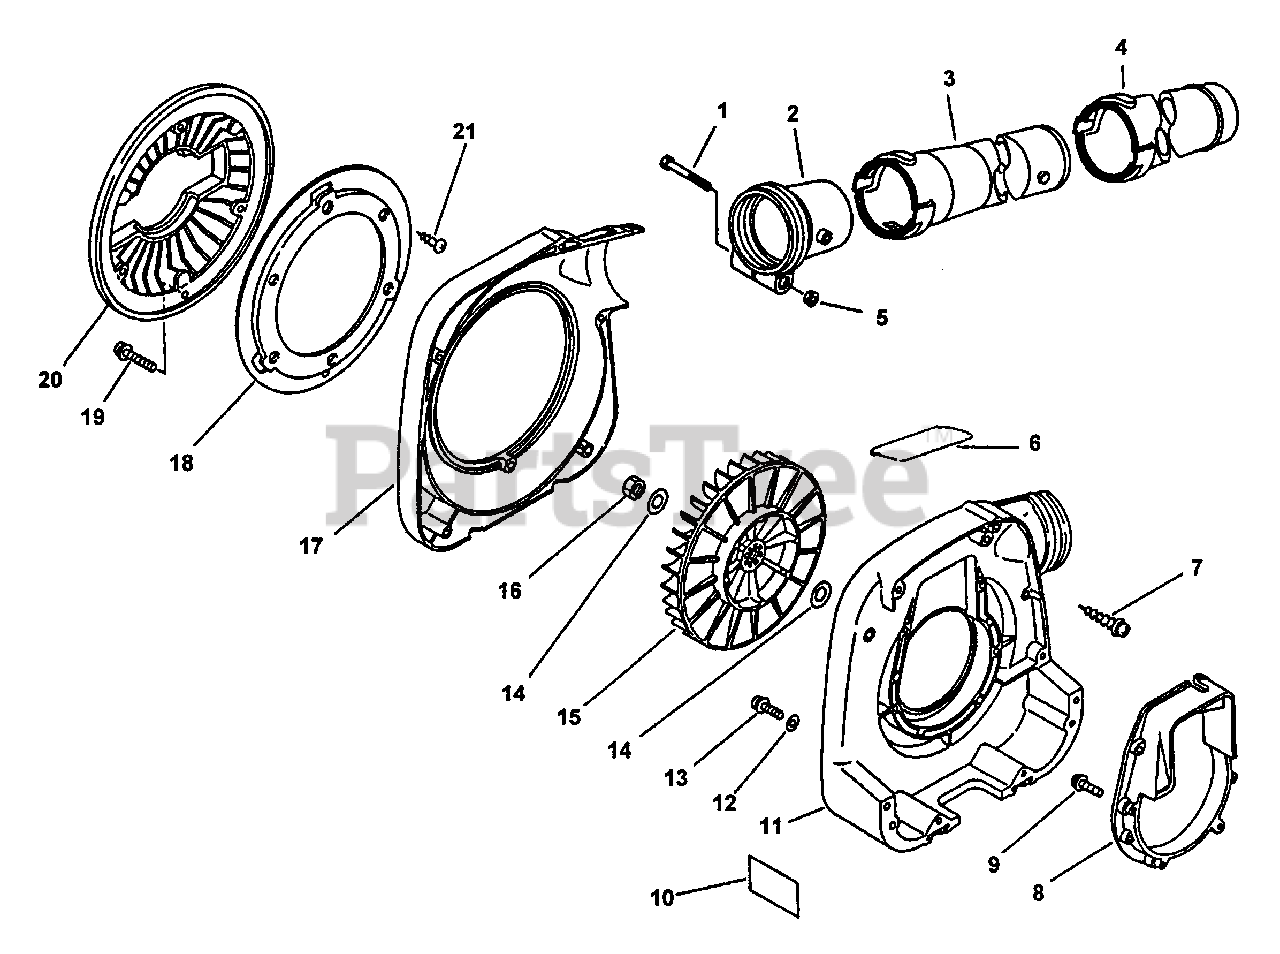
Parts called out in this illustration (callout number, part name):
1	SCREW - 5×60
2	ADAPTER, TUBE
3	TUBE, BLOWER - STRAIGHT
4	TUBE, BLOWER - NOZZLE
5	NUT, FLANGE M5
6	LABEL - NOISE
7	SCREW 5×30
8	BRACKET, ENGINE
9	SCREW 4×18
10	LABEL - CAUTION
11	CASE, FAN
13	SCREW 4×22
15	FAN
17	COVER, FAN - LEFT
18	BASE, GRID
19	SCREW 5×16
20	SHIELD, DEBRIS
21	SCREW 4×10
